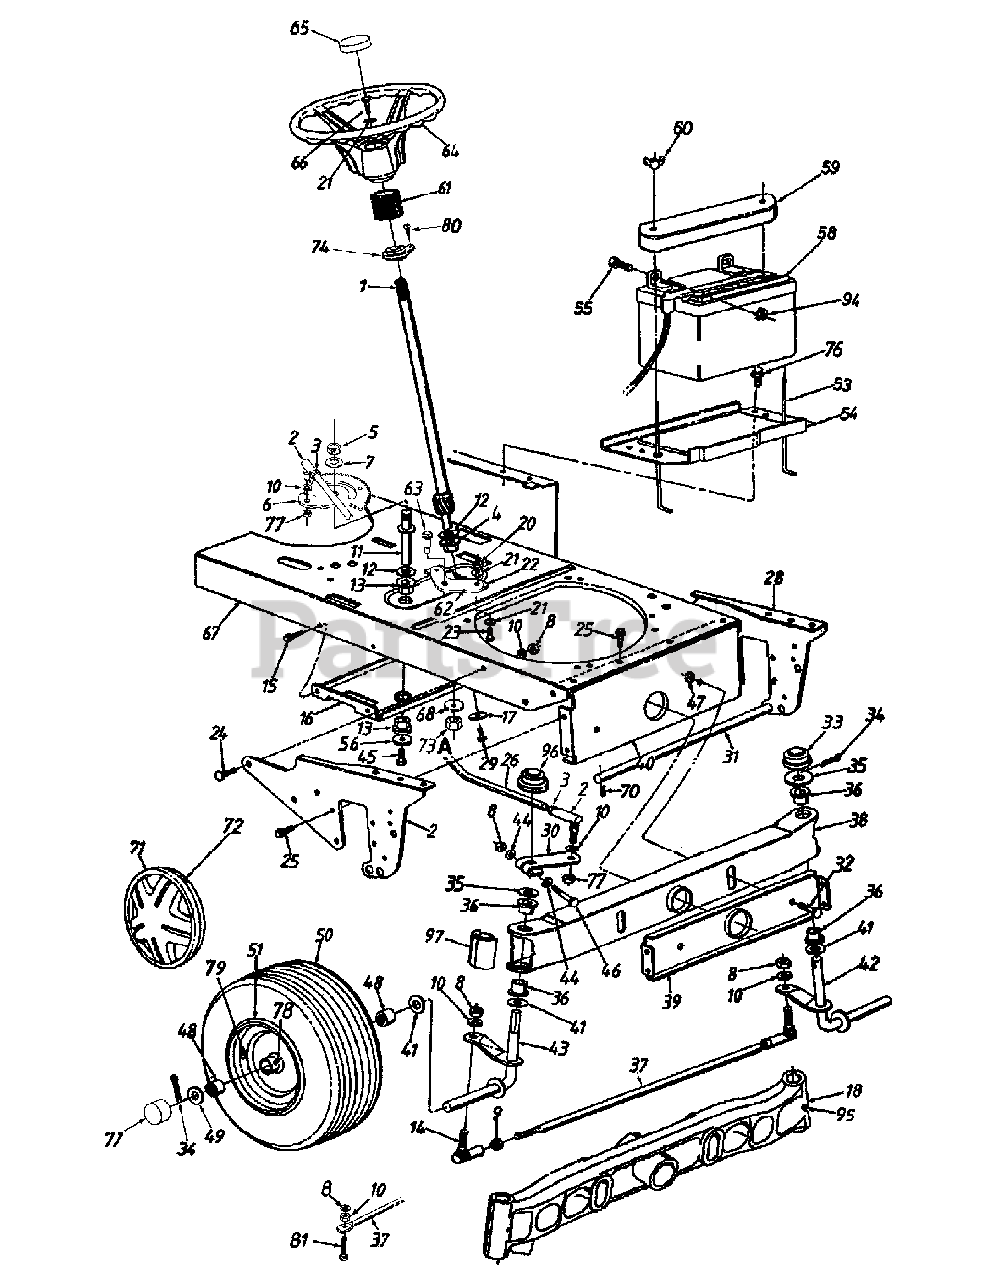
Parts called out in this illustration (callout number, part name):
1	Steering Shaft Ass'y.
2	Ball Joint 7/16-20 Thd.
3	Hex Jam Nut 7/16-20 Thd.
4	Hex Flange Brg.
5	Hex Jam Nut 5/8-18 Thd.
6	Steering Gear Segment
7	Bell-Wash. 5/8" I.D. x 1.25" O.D.
8	Hex Nut 3/8-24 Thd.
9	Hex Jam Nut 3/8-24 Thd.
10	L-Wash. 3/8" I.D.
11	Steering Gear Segment Shaft
12	Fl-Wash. .64" I.D. x 1.24" O.D.
13	Hex Flange Brg. .63" I.D.
14	Ball Joint Ass'y.
15	Hx Wash. Hd. TT-Tap Scr. 1/4-20 x .5" Lg.
17	Cap
18	Pivot Bar Ass'y. (Cast Iron)
20	Hex Nut 5/16-24 Thd.
21	Bell-Wash. .345" I.D. x .88" O.D.
24	Ribbed Neck Bolt 3/8-24 x .8" Lg.
25	Hex Wash. TT-Tap Scr.5/16-18 x .62" Lg.
26	Steering Drag Link
31	Deck Connecting Rod
32	Shld. Bolt .498" Dia. x 2.45" Lg.
33	Cap
34	Cotter Pin 5/32" Dia.
35	Flat Washer
36	Flange Brg. .757" I.D.
37	Tie Rod (Adjustable)
41	Fl-Wash. .76" I.D. x 1.49" O.D.
42	Front Axle Ass'y.-L.H.
43	Front Axle Ass'y.-R.H.
44	Bowed Washer
45	Hex L-Scr. 5/16-18 x .62" Lg.
46	Hex Bolt 3/8-24 x 2.25" Lg.
47	Hex L-Nut 3/8-16 Thd.
48	Flange Brg. .75" I.D.
49	Fl-Wash. .71" I.D. x 1.5" O.D.
56	Fl-Wash. .33" I.D. x 1.25" O.D.
58	Battery
59	Battery Cover
60	Wing Nut Plastic 1/4-20 Thd.
61	Steering Bellow (Style 0, 3, 5, 9)
65	Steering Cap (Round)
66	Hex L-Bolt 5/16-18 x 1" Lg.
70	Internal Cotter Pin
71	Hub Cap
72	Spring Clip
73	Hex Nut 3/8-16 Thd.
74	Flange Bearing (Style A)
76	Hex Wash. B-Tap Scr. 1/4 x .62" Lg.
77	Hex Jam L-Nut 3/8-24 Thd.
78	Grease Fitting
79	Air Valve
80	Oval Hd. Cr.-Sunk Scr. #10 x 5/8" Lg. (Style A)
81	Hex Bolt 3/8-24 x 1.5" Lg. (Gr. 5)
94	Hex L-Nut 1/4-20 Thd.
95	Grease Fitting
97	End Cap
